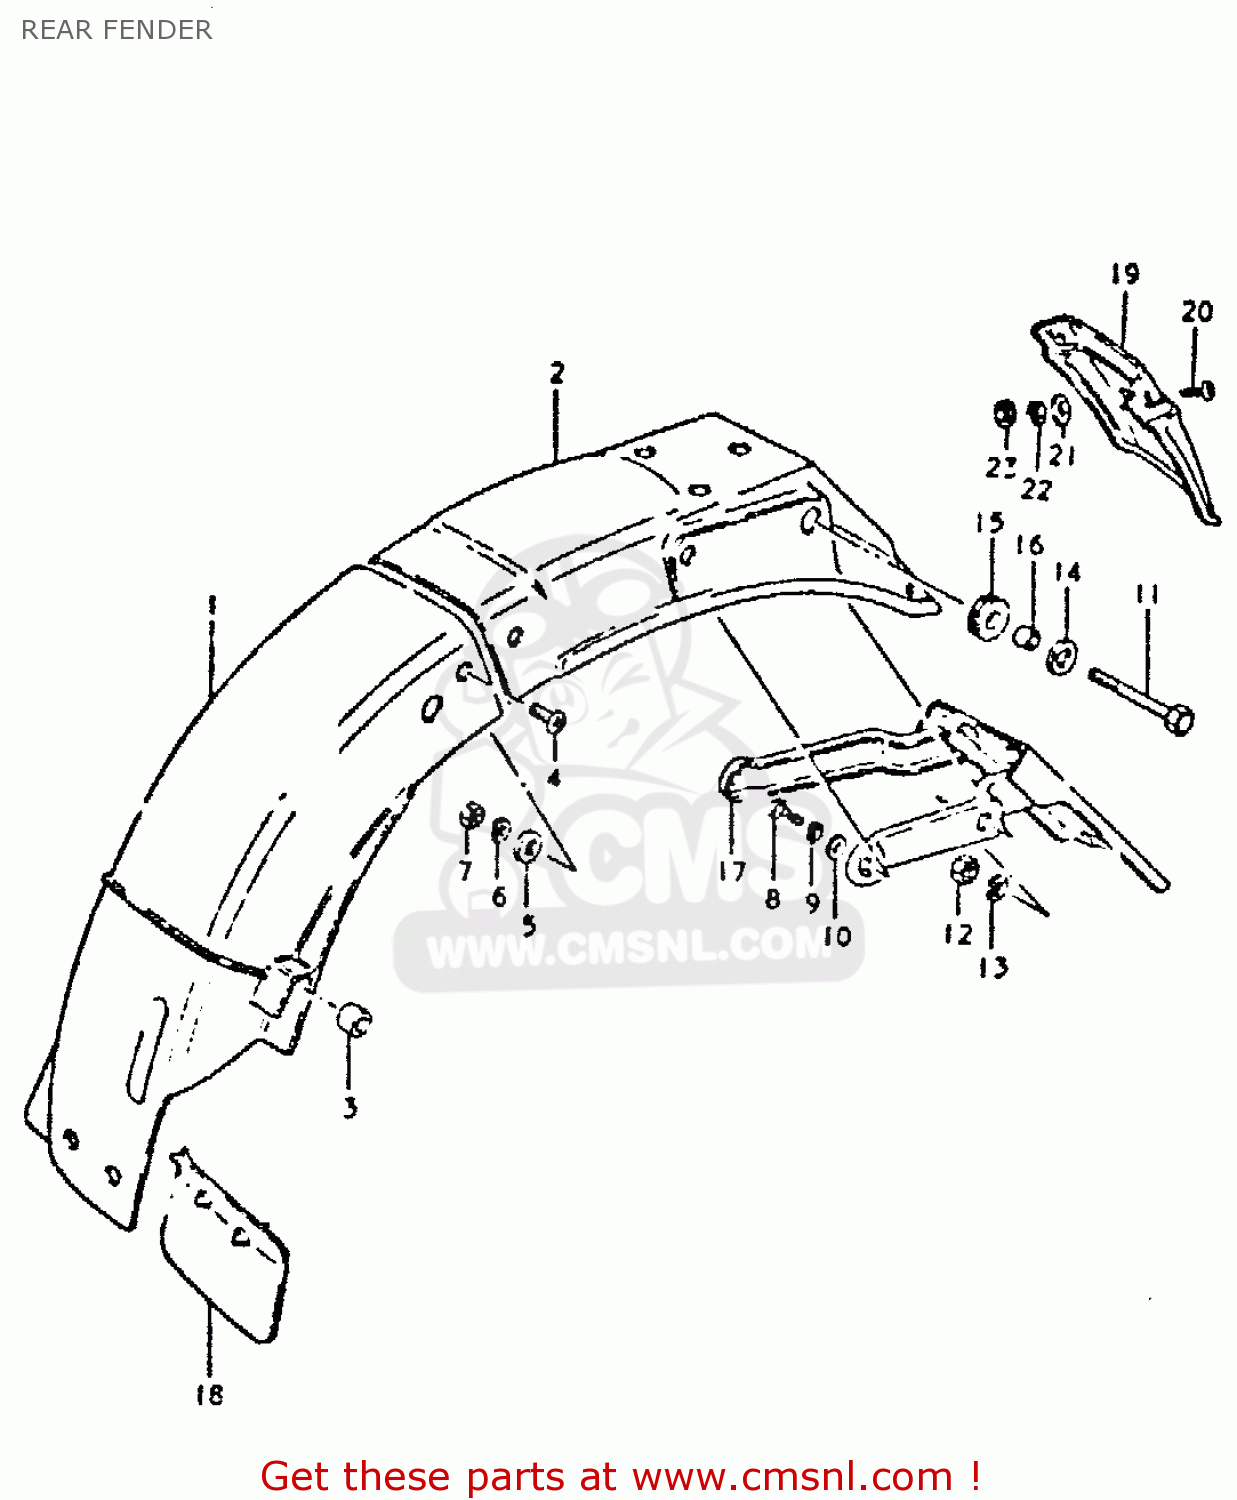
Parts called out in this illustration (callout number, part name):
1	FENDER,REAR
2	BODY,REAR FENDER,REAR
3	CUSHION
4	SCREW
5	WASHER (5.5X16X1.2)
6	LOCK WASHER
7	NUT
8	BOLT, UPPER
9	LOCK WASHER
10	WASHER
11	BOLT
12	NUT
13	LOCK WASHER
14	WASHER(8.5X26X1.2)
15	CUSHION
16	SPACER (8.2X12X7.5)
17	REINFORCEMENT,REAR FENDER
18	GUIDE,RR FENDER MUD
